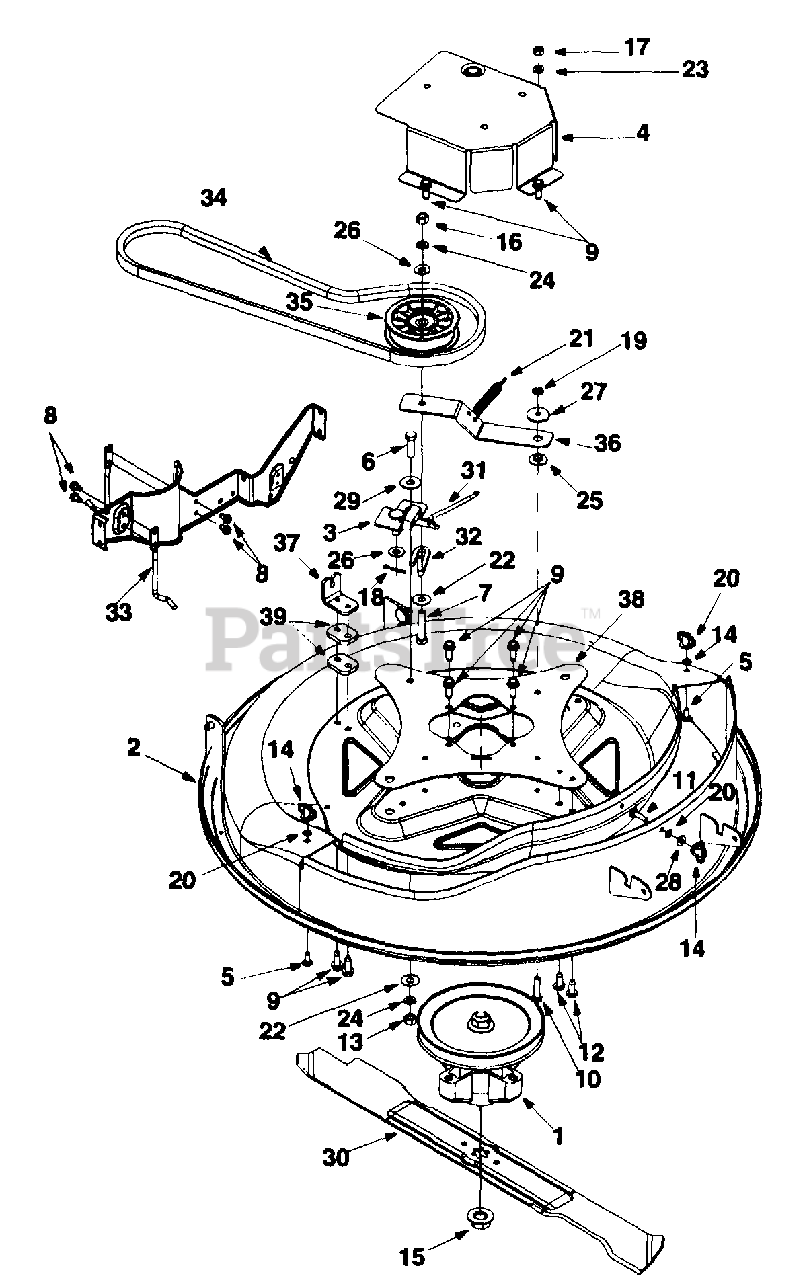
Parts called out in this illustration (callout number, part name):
1	Spindle Assembly
2	Deck Assembly: Yellow
3	Brake Bracket Assembly
5	Carriage Screw 1/4-20 x .62
6	Hex Bolt 3/8-24 x 1.25 Grade 8
7	Hex Screw 3/8-16 x 1.75 Gr. 5
8	Self-Tapp. Screw 1/4-20x.5
9	Self-Tapp. Screw 5/16-18x.75
10	Hex Cap Scr. 5/16-24 x 1.25
11	Carriage Screw
12	Torx Screw 5/16-18 x .75
13	Hex Nut 3/8-24
14	Wing Nut With Bell Washer
15	Flange Nut 5/8-18
16	Hex Nut 3/8-16
17	Hex Nut 5/16-24
18	Cotter Pin
19	Speed Nut
21	Extension Spring
22	Flat Washer 3/8 x 1.00 x .030
23	Lock Washer 5/16
24	Lock Washer 3/8
25	Bushing
26	Flat Washer .406 x .875 x .059
27	Flat Washer .330 x 1.25 x .120
28	Flat Washer
29	Spacer
32	Belt Keeper
35	Flat Idler Pulley
